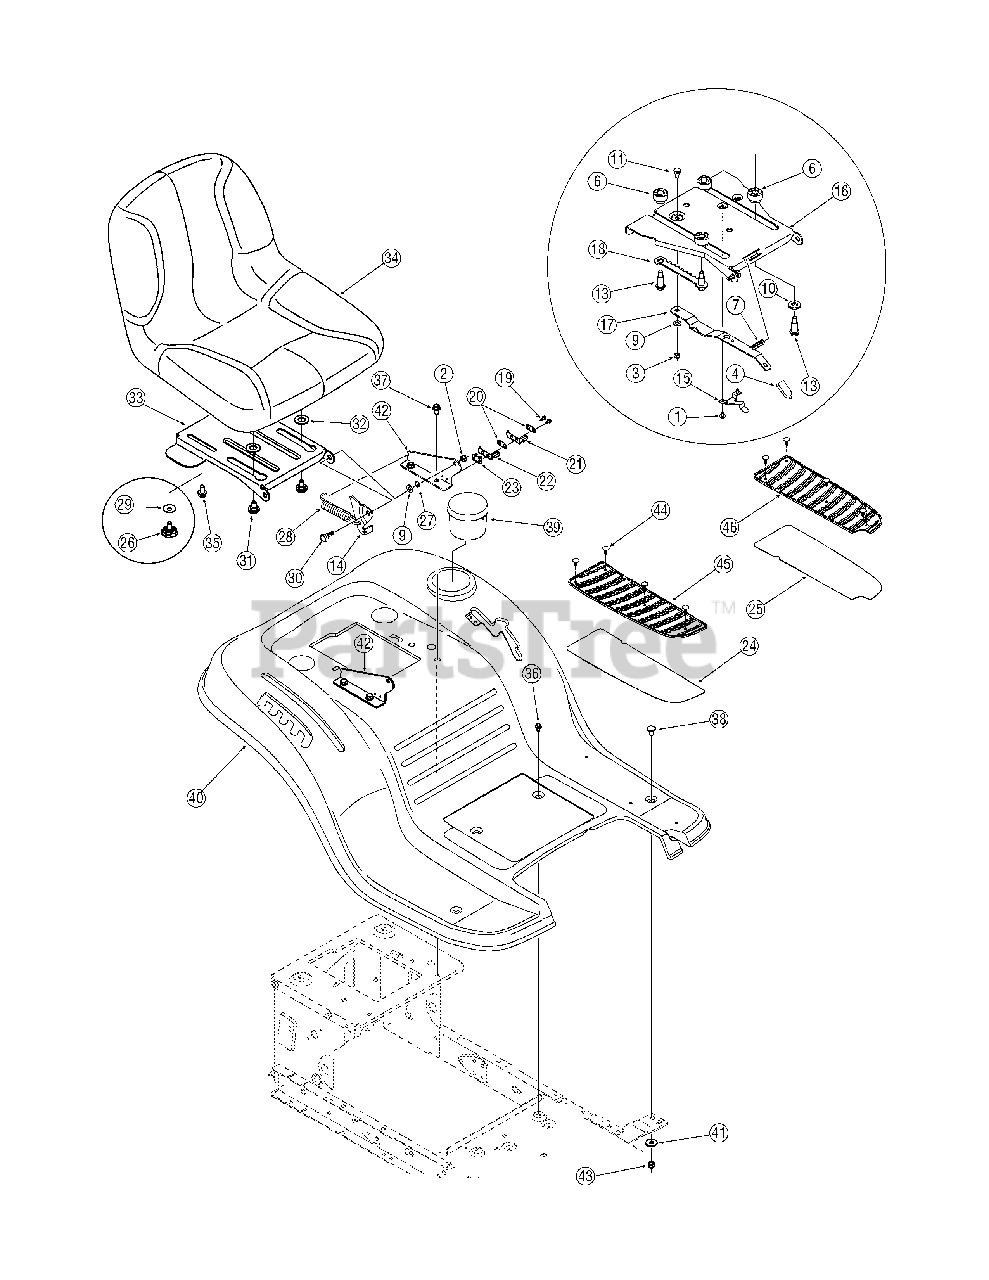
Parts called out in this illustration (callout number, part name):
1	Screw, #10-16, .375
2	Nut, Flange Lock, 5/16-18, GrF, Nylon
3	Nut, Flange Lock, 1/4-20
4	Seat Adjuster Grip
5	Nut, Speed, .3125 ID
6	Spacer
7	Compression Spring, .41 x 1.5
8	Spring, Extension, .84 Dia. x 4.6
9	Wash, Flat, .344 x .688 x .065
10	Wash, Flat, .531x 1.062 x.134
11	Screw, Shoulder, .340 x .285,1/4-20
12	Screw, Shoulder, .437 x .268, 5/16-18
13	Screw, Shoulder, .50 x .925, 3/8-16
14	Seat Bracket, Lift
15	Seat Stop
18	Seat Adjustment Selector
19	Screw, #8-18 x .50
20	Plate, Insulator
21	Spring Switch, Inner
22	Spring Switch, Outer
23	Plate, Insulator Boss
24	Foot Pad, Abrasive, RH
25	Foot Pad, Abrasive, LH
26	Knob, 3/8-16, .625
27	Nut, Speed, .3125 Id
28	Spring, Extension, .84 Dia x 4.6 .
29	Washer, Flat, .406 x 1.00 x .030
30	Screw, Shoulder, .437 x .268, 5/16-18
31	Screw, Shoulder, .625 x .175, 3/8-16
32	Washer. Thrust, .635 x 1.26 x .06
34	Seat, Low Back
34	Seat, Medium Back
35	Screw, 3/8-16, .625
36	Screw, 1/4-20, 0.500
37	Screw, 5/16-12, 0.750
38	Screw, Carriage, 1/4-20, .62 Gr2
39	Cup Holder
41	Washer, Flat, .28 x .74 x .063
43	Nut, Flange Lock, 1/4-20, GrF, Nylon
44	Clip, Ratchet, .250 Dia
45	Foot Pad, RH
46	Foot Pad, LH
